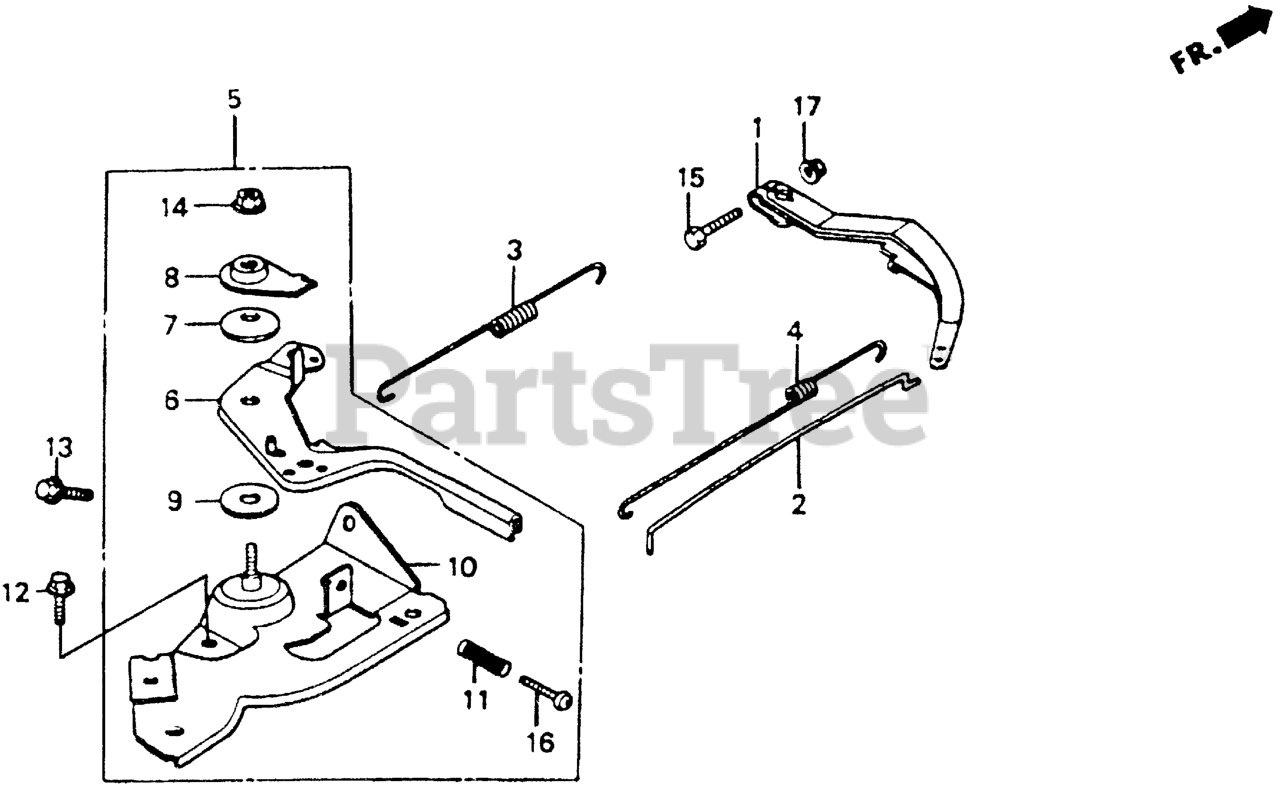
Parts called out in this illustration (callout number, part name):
1	ARM, GOVERNOR
2	ROD, GOVERNOR
3	SPRING, GOVERNOR
4	SPRING, THROTTLE RETURN
5	CONTROL ASSY. (STD) Use up to Engine SN 1379409.
5	CONTROL ASSY. Use from Engine SN 3172542.
5	CONTROL ASSY.
6	LEVER, CONTROL
7	SPRING, LEVER
8	WASHER, CONTROL LEVER
9	SPACER, CONTROL LEVER
10	BASE, CONTROL Use from Engine SN 3172542.
11	SPRING, CONTROL ADJUSTING Use from Engine SN 2327377.
12	BOLT, FLANGE (6X12) (CT200)
13	BOLT, FLANGE (6X12) (CT200)
14	NUT, SELF-LOCK (6MM)
14	NUT, FLANGE (6MM)
15	BOLT, GOVERNOR ARM
15	BOLT, HEX. (6X20)
16	SCREW, PAN (5X20)
16	SCREW, PAN (5X25)
17	NUT, FLANGE (6MM)
